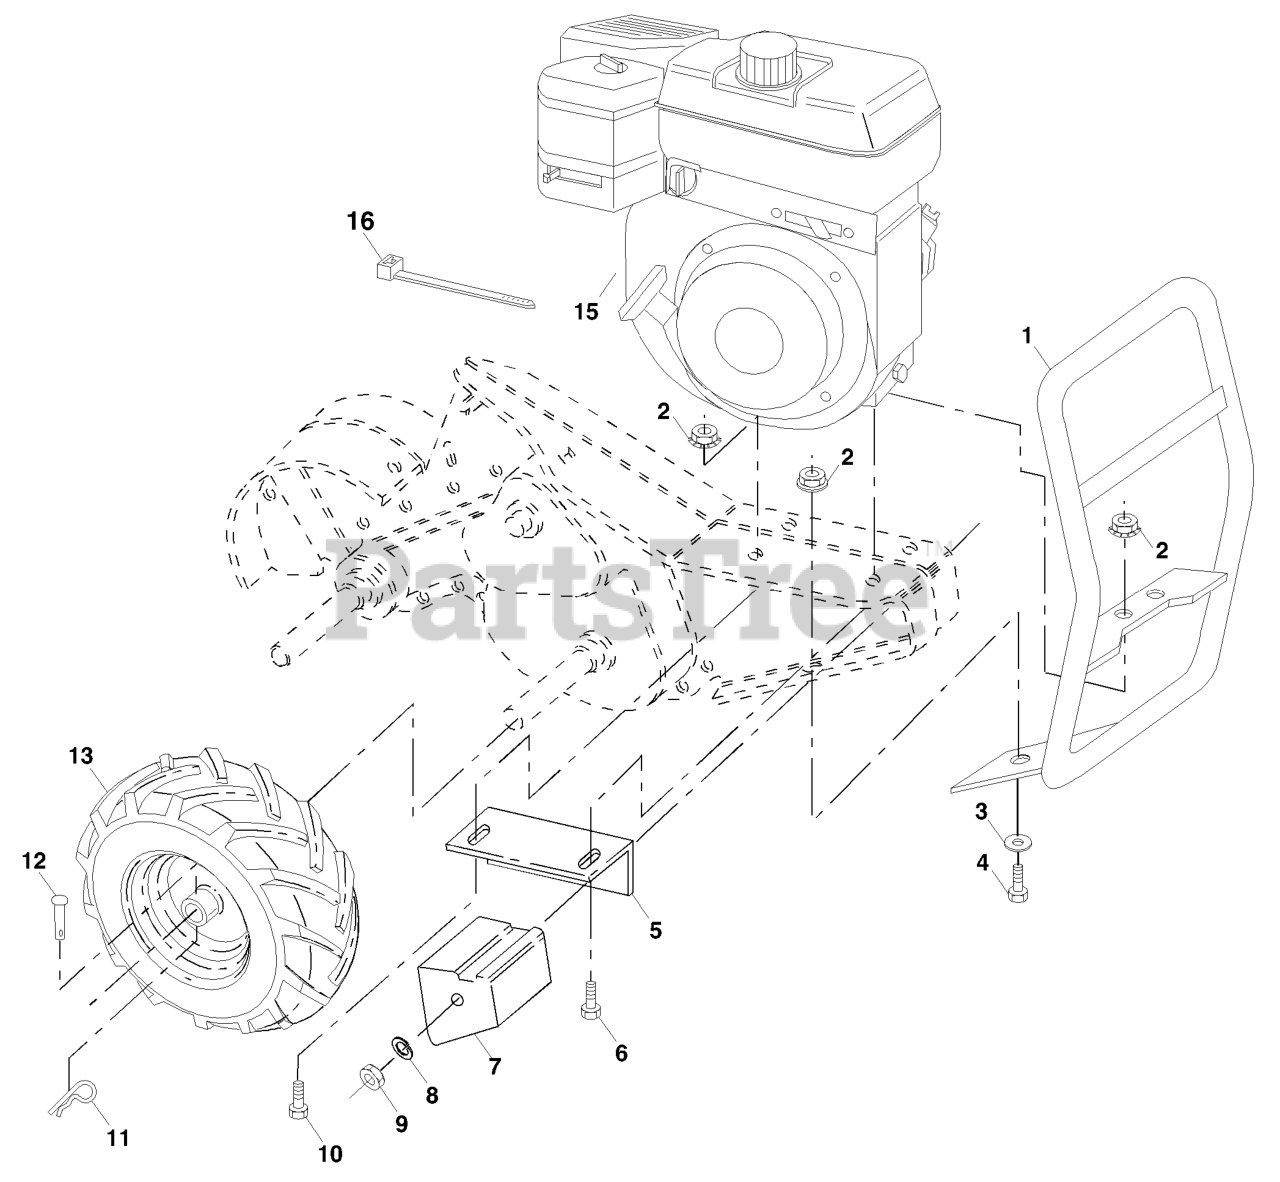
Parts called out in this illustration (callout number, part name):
1	BUMPER
2	LOCKNUT-FLANGE 5/16-18
3	WASHER
4	BOLT
5	DNO BRACKET RH CRT
6	Bolt, Hex 5/16-18 x 2
7	COUNTERWEIGHT, RH
8	WASHER, LOCK 3/8
9	NUT.HEX.3/8-16UNC
10	BOLT
11	RETAINER M
12	RIVET,DRILLED
13	TIRE.16X4-8.CHEVRON.TILLER
13	RIM
13	VALVE STEM LT
16	TIE GUIDE
